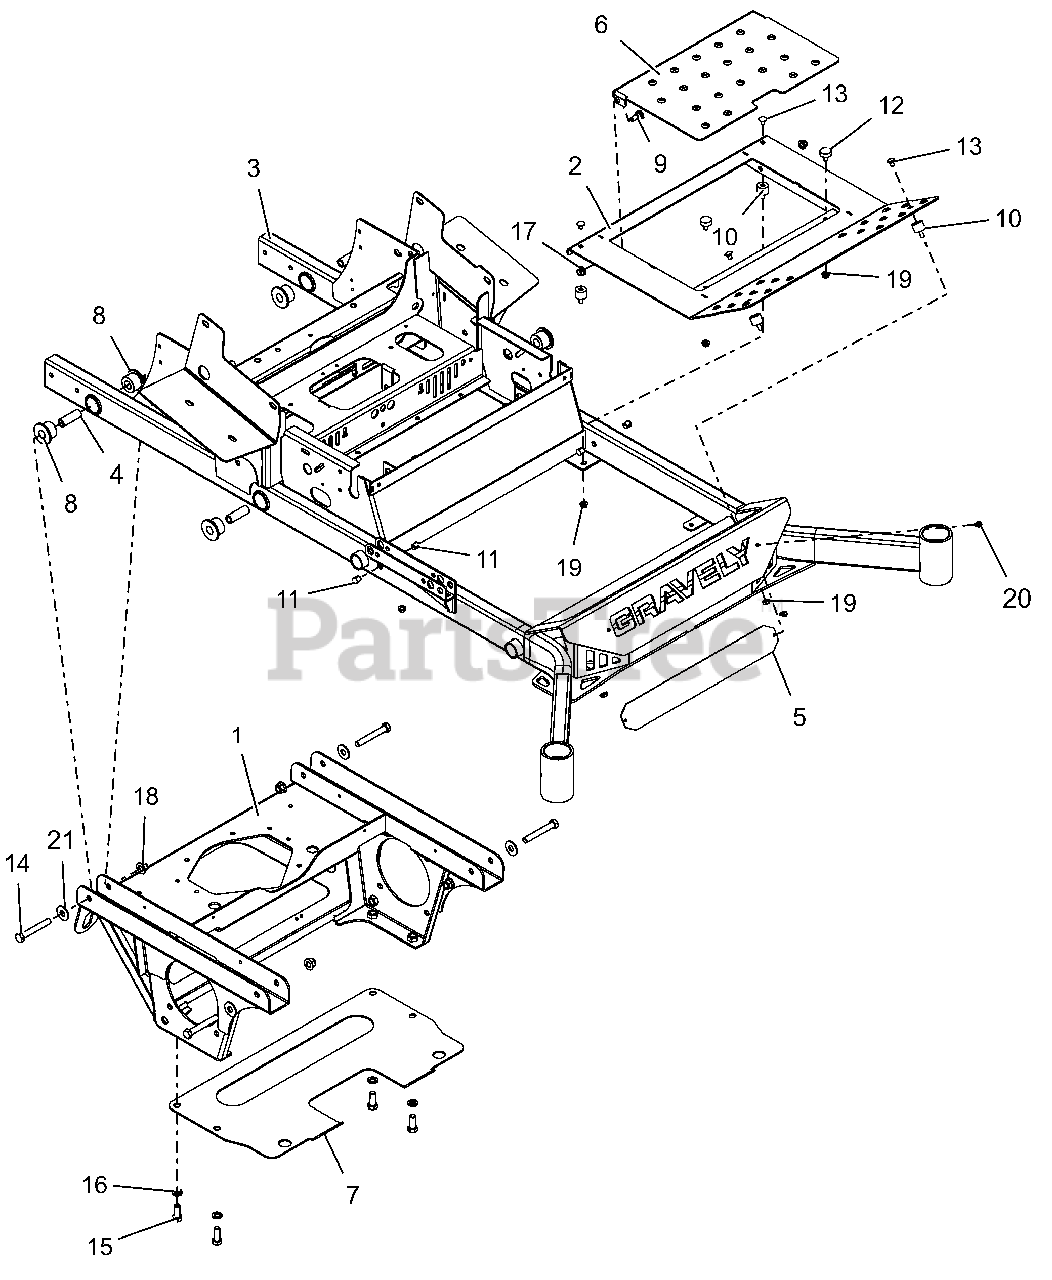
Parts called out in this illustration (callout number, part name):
1	PT200/400 AXLE/ENG FRM WMT-RED
2	FOOTPLATE WLDMT W/SAFETY DECAL
3	72" PT200/400 FRAME W/DECALS
4	BSHG-SLV .50X.75X2.23
5	BUMPER LOGO BACKING PLATE -BLK
6	INSPECTION PANEL W/SAFTY DECAL
7	PLATE-TRANSMISSION SKID
8	BSHG-FLG .75X1.51X1.13X2.0 URE
9	BLT,SHLDR EP .38-16X.30 HEX YZ
10	BUMPER,STUD MNTD W/FEMALE INSR
11	PLUG, HOLE .50
12	BUMPER, RUBBER
13	@BLT-RDHDSQNK .31-18X.50 G5YZ
14	@BLT-HEX .50-13X3.50 GR5 YWZC
15	@BLT-HEX .50-13X1.25 GR5 YWZC
16	@WSHR-LK .50X.125 REG YWZC
17	@NUT-LK-NYL-FLG .38-16 YWZC
18	@NUT-LK-NYL-FLG .50-13 YWZC
19	@NUT-SPNLK-FLG .312-18 YWZC
20	SCR-TAP .25-20X.50 HWH TR YWZ
21	@WSHR-FL-STL.563X1.38X.109YWZC
